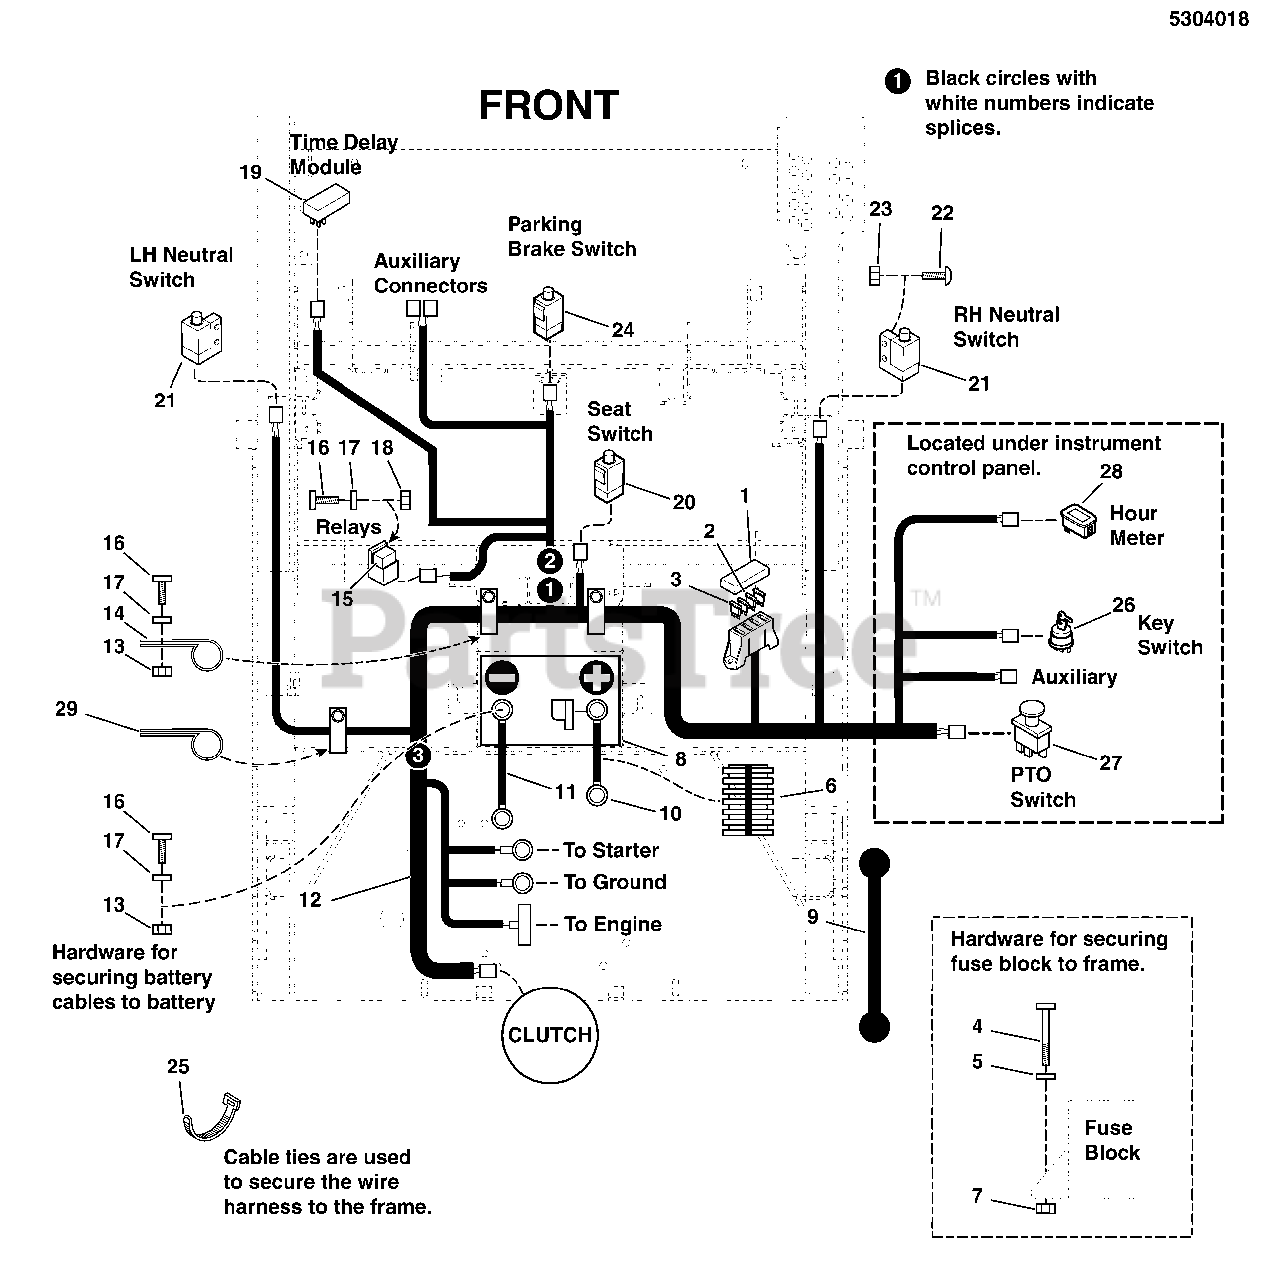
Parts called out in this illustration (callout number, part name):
1	COVER, VINYL FUSEBLOCK
2	FUSE, ATO-15 (15 AMP)(SV)
3	FUSE, ATO-20 (20 AMP)(SV)
4	SCREW, #10-24 X 2 ROUND PHILLIPS
5	WASHER, #10 SAE
6	WIRE LOOM, 3/8 ID X 17 IN
7	NUT, #10-24 HEX NYLON LOCK
8	BATTERY, 11U1L, 350 CCA
9	STRAP-BLACK RUBB
10	BATTERY CABLE, NEG, 14, 5/16-13/32
11	BATTERY CABLE, POS, 22, 1/4-5/16
12	WIRE HARNESS, S200XT BRIGGS BIG BLOCK
13	NUT, 1/4-20 HEX NYLOCK FLANGE
14	CLAMP, VINYL INSULATED
15	RELAY, 12V, 40A
16	BOLT, 1/4-20 X 3/4 GD5 CZ
17	WASHER, 1/4 SAE
18	NUT, 1/4-20 HEX SERR. FLANGE
19	MODULE, TIME DELAY
20	SWITCH, PLUNGER, NO/NO SNAP-IN
21	SWITCH, PLUNGER, N.O.
22	SCREW, #10-24 X 3/4 ROUND PHILLIPS
23	NUT, #10-24 HEX
24	SWITCH, DP NO/NC SNAP-IN
25	TIE, SELF-LOCKING, 12"
26	SWITCH, IGNITION, 6 POST (SEE INSTRUMENT CONTROL PANEL GROUP)
27	SWITCH, BLADE ENGAGEMENT (SEE INSTRUMENT CONTROL PANEL GROUP)
28	HOUR METER (SEE INSTRUMENT CONTROL PANEL GROUP)
29	CLAMP, VINYL INSULATED, .625
